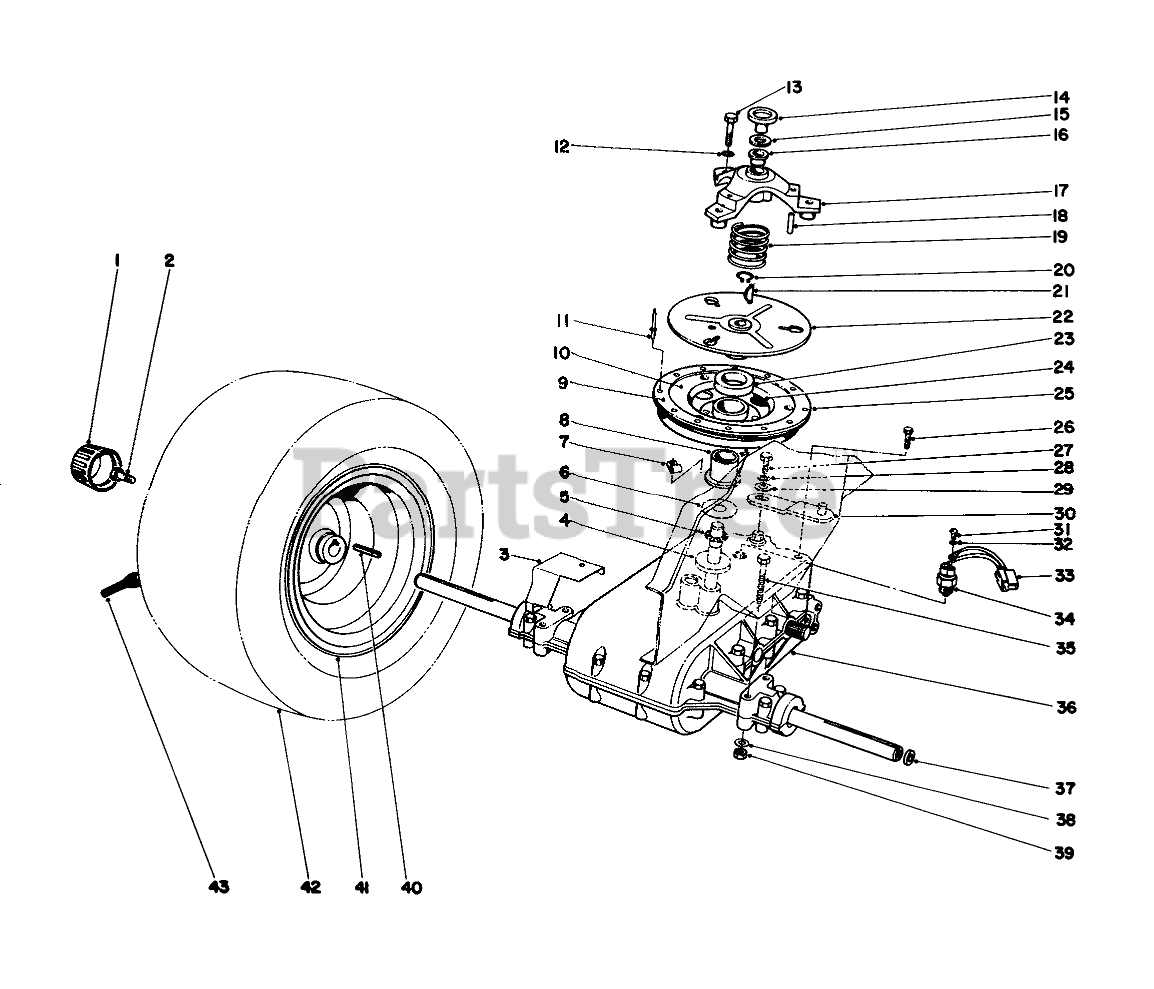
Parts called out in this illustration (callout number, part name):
1	Cap-Hub
2	CAPSCREW 3/8 16 3/4
3	GRASS SHIELD B
4	SPACER
5	NEEDLE BRG
6	THRUST WASHER
7	Clamp (Incl. with Main Wire Harness)
9	CLUTCH PAD
10	RETAINER RING R
11	Rivet
12	WASHER-LOCK
13	SCREW-HH
14	CLUTCH CAP
15	THRUST RACE
16	BUSHING-FLANGE
17	Clutch Cover (Incl. Ref. #16 & 18)
18	NEEDLE BRG
19	COMPRESSION SPRING
20	RING-SNAP, EXTERNAL
21	KEY-WOODRUFF
22	Clutch Plate
23	WASHER FELT
25	Sheave Assembly (Incl. Ref. #8-11)
26	SCREW-HWHTF
27	SCREW-HH
28	WASHER-LOCK
29	WASHER-FLAT
30	SHIFT LEVER WA B
31	SCREW
32	WASHER-LOCK/INT
33	WIRE HARNESS
34	NEUTRAL SWITCH
35	SCREW-HH
36	TRANSAXLE
37	SPACER-WHEEL
38	WASHER-PLAIN
39	NUT-LOCK, NI
41	WHEEL ASM
43	STEM-VALVE
